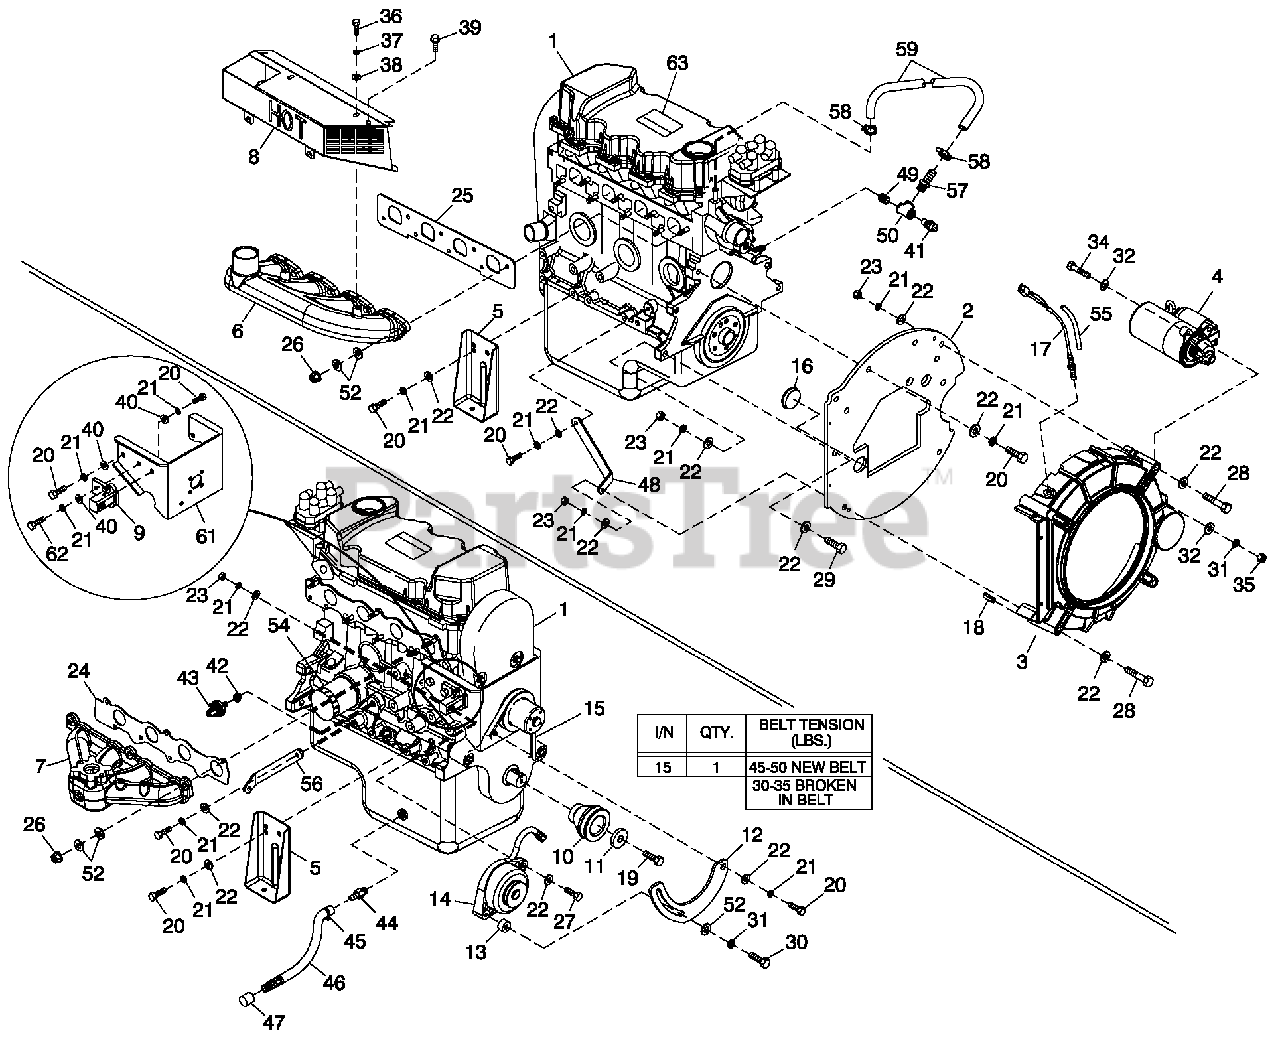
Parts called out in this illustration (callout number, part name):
1	ENGINE GENERAC 1.6L NG
2	ENGINE PLATE 1.6L (TO BE USED WITH PLATE SPACER P/N 0G2070.)
3	HOUSING BLOWER MACHINED 1.6L
4	STARTER MOTOR 12V
5	ENGINE MOUNTING FOOT STAMPING
6	EXHAUST MANIFOLD 1.6L MACHINED
7	INTAKE MANIFOLD MACHINED 1.6L
8	SHIELD 1.6L EXHAUST HEAT
9	DC ALTERNATOR ADAPTER MACHINED
10	PULLEY CRANKSHAFT MACHINED (3600RPM)
11	WASHER PULLEY
12	BRACKET TENSIONER DC ALT
13	SPACER ALTERNATOR
14	DC ALTERNATR HAN-KOK
15	V-BELT 3/8 X 30.6 (3600RPM)
16	CAP, 1.5" HOLE SHALLOW
17	VR SENSOR ASSY 3/8-24 LOW SENS
18	PIN SPRING 1/4 X 3/4
19	SCREW HHC M12-1.5 X 40 G10.9
20	SCREW HHC M10-1.5 X 25 G10.9
21	WASHER LOCK M10
22	WASHER FLAT 3/8-M10 ZINC
23	NUT HEX M10-1.5 CLASS 10 ZINC
24	GASKET INTAKE MANIFOLD 1.6L
25	GASKET EXHAUST MANIFOLD 1.6L
26	NUT TOP LOCK FL M8-1.25
27	SCREW HHC M10-1.5 X 70 G8.8
28	SCREW HHC M10-1.5 X 110 G10.9
29	SCREW HHC M10-1.5 X 40 G10.9
30	SCREW HHC M8-1.25 X 35 G8.8
31	WASHER LOCK M8-5/16
32	WASHER FLAT 5/16-M8 ZINC
33	TIE WRAP UL 7.4" X .19" BLK
34	SCREW HHC M8-1.25 X 40 G8.8
35	NUT HEX M 8-1.25 G8 CLEAR ZINC
36	SCREW HHC 1/4-20 X 1/2 G5
37	WASHER LOCK M6-1/4
38	WASHER FLAT 1/4-M6 ZINC
39	SCREW HHTT M6-1.0 X 12 ZINC
40	WASHER FLAT M10 HEAVY DUTY
41	SWITCH HI-TEMP 245 D X 3/8 NPT
42	BSHG RDCR HEX 1/4 TO 1/8
43	SWITCH OIL PRESSURE 10PSI2POL
44	ADAPTER DRAIN OIL
45	CLAMP HOSE - OIL DRAIN
46	HOSE OIL DRAIN ASSY 21"
47	CAP HEX 1/4 NPT BRASS
48	STRUT LH 1.6L ENG ADAPT PLATE
49	NIPPLE PIPE 3/8 NPT X 1-1/2
50	PIPE TEE 3/8 NPT
51	SCREW HWHTF M6-1.0 X 16
52	WASHER FLAT .34 ID X .75 OD
54	OIL FILTER 1.6L
55	CONDUIT FLEX .25"ID (6" LG)
56	STRUT RH 1.6L ENG ADAPT PLATE
57	BARBED STR 3/8 NPT X 3/8
58	CLAMP HOSE .38-.87
59	HOSE 3/8 ID LOW PRES OIL/WATER (11" LG)
61	BRACKET FAN ALT ADAPTER 1.6L
62	SCREW HHC M10-1.5 X 35 G8.8
63	DECAL EMISSION CTRL INFO 1.6L
